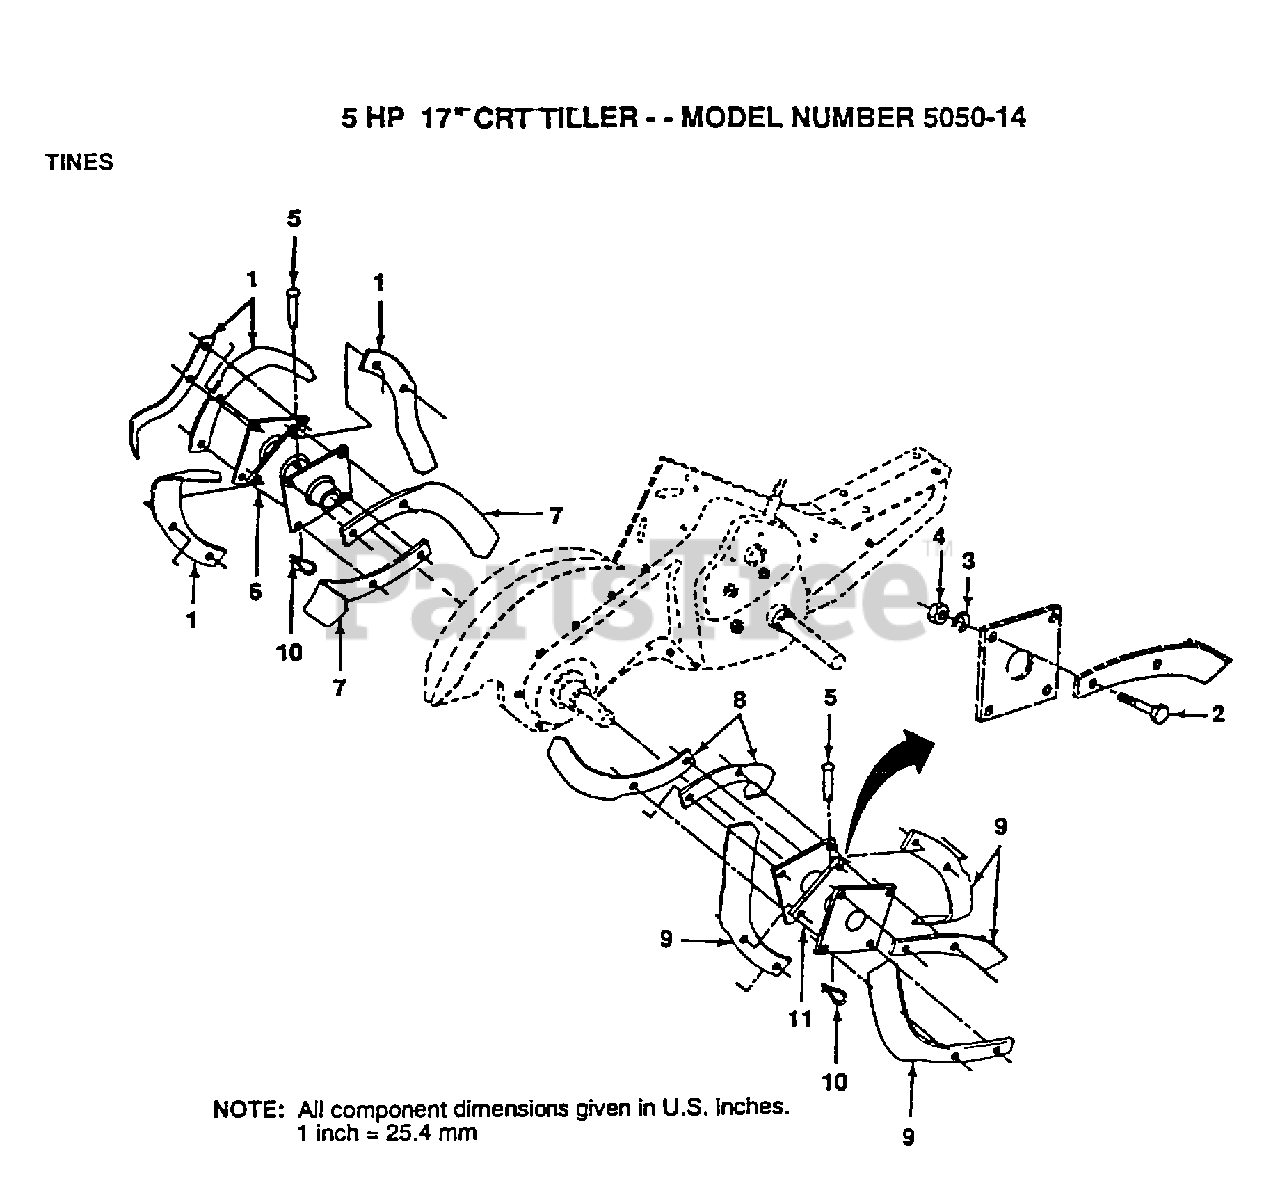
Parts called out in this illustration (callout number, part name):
2	BOLT
3	LOCKWASHER
5	RIVET.PAN HD.1.75
6	TINE ASSY LH CRT
7	"TINE.LH.12"""
8	"TINE.RH.12"""
10	RETAINER.SPRING
11	TINE ASSY RH CRT
